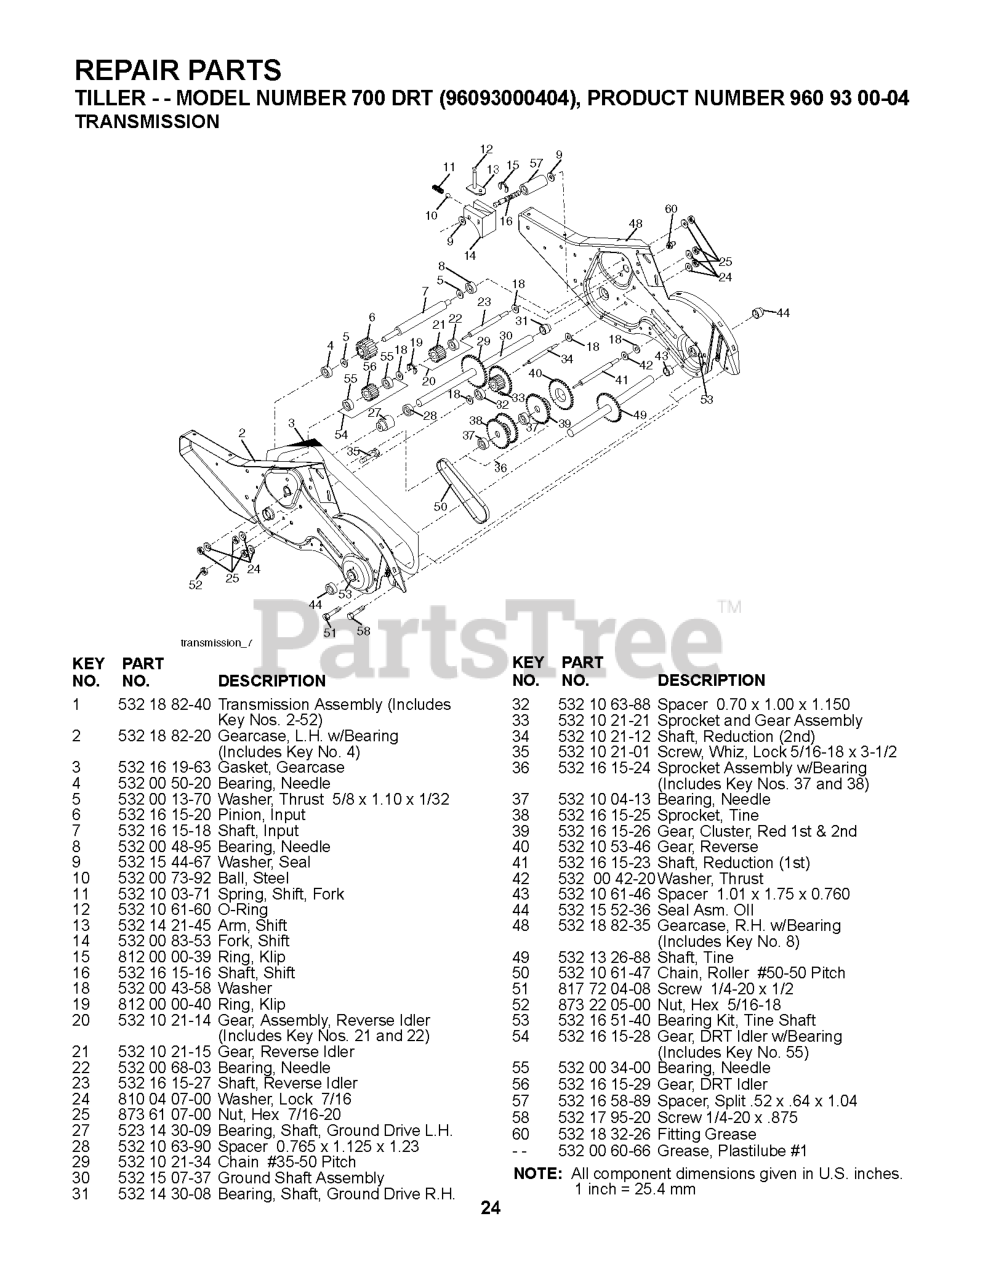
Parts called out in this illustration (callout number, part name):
1	TRANSMISSION.ASM.17
2	GEARCASE.ASM.DRT.LH.
3	GASKET
4	NEEDLE BRNG LT
5	THRUST WASHER
6	GEAR.PINION.INPUT.DRT
7	SHAFT.INPUT.D.9TEETH
9	WASHER, SEAL (2 2)
10	BALL, STEEL
11	SPRING-SHIFT CRT
13	BRACKET ASM.SHIFT.CRT
14	SHIFT FORK TI
16	SHAFT.SHIFT.DRT
20	GEAR ASSY CRT
21	GEAR-REV IDLR CRT
22	NEEDLE BEARING TI
23	SHAFT.IDLER.REVERSE.CRT
24	LOCKWASHER
25	NUT.ASF.HEX.7/16
27	BEARING, SHAFT, GROUNDDRIVE LH
30	GROUND SHAFT ASS'Y
31	BEARING, SHAFT RH CRT
33	SPRCKT 8 GEAR CRT
34	SHAFT.SECONDARY.REDUCTION.CRT
35	SCRW WHIZ LOK CRT
36	GEAR & SPROCKET.ASM.WBEARIN
37	BEARING.NEEDLE.CRT
38	ASM.GEAR & SPROCKET
39	GEAR.CLUSTER.DRT.TILLER
41	SHAFT.REDUCTION.FIRST.DRT
42	BRNG RACE T
44	SEAL ASM, OIL
48	GEARCASE.ASM.DRT.RH.
49	TINE SHAFT
50	CHAIN.TILLER
51	SCREW
53	KIT.BEARING.TILLER.
54	GEAR.ASM.DRT.TILLER
55	BEARING.NEEDLE
56	GEAR.DRT.IDLER
57	SPACER.SPLIT
58	BOLT SHOULDER 1/4-20 UNC X.875
60	FITTING.GREASE.TAPERED
